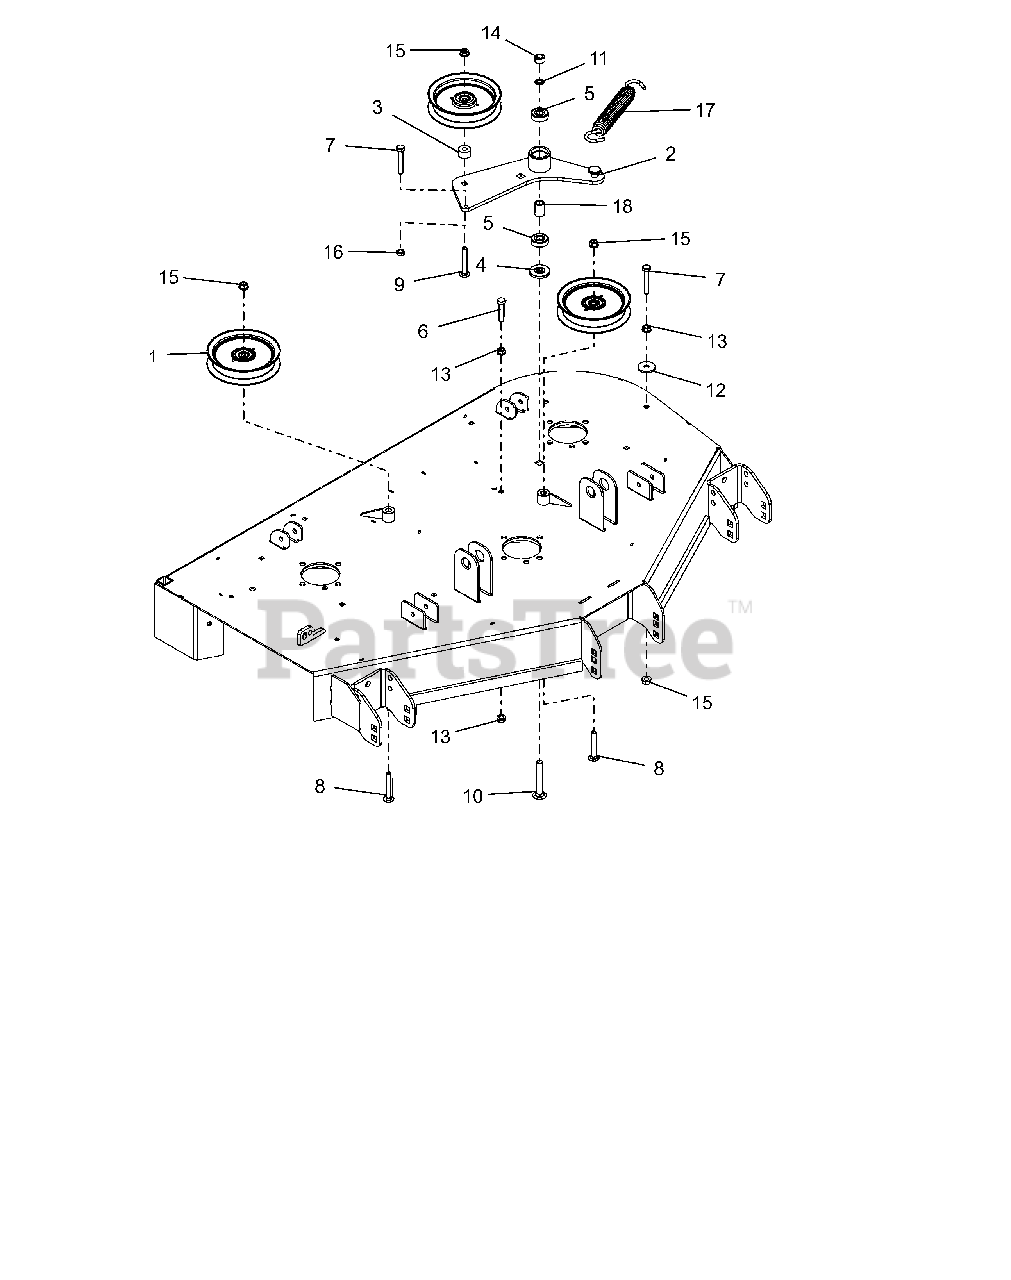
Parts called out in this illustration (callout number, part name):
1	IDLER, FLAT 5.00"
2	WLDMT, IDLER ARM
3	SPACER .390X1.000X.562
4	SPACER, IDLER ARM
5	BRG-BALL .500X1.38X.437
6	BLT, HEX .38-16X1.75F G5 ZCC
7	BLT,HEX .38-16X2.25 G5 ZCC
8	BLT,RHSN .38-16X2.50 G5 ZCC
9	BLT, RHSSN.38-16X2.50 G5 ZCC
10	BTL,RHSSN .500-13 X 3.25 G5 ZCC
11	WASHER, .500X.750X.020 THRUST
12	WSHR,FLT .406X1.375X.135 ZCC
13	NUT, SPNLK-FLG .38-16 G5 ZCC
14	NUT,LK-CTR .50-13 GA ZCC
15	NUT-LK-CTR-FLG .375-16 GF ZCC
16	NUT-JAM .375-16 G2 ZCC
17	SPRING, EXTENSION
18	SPACER .510 X .75 X 1.1485
